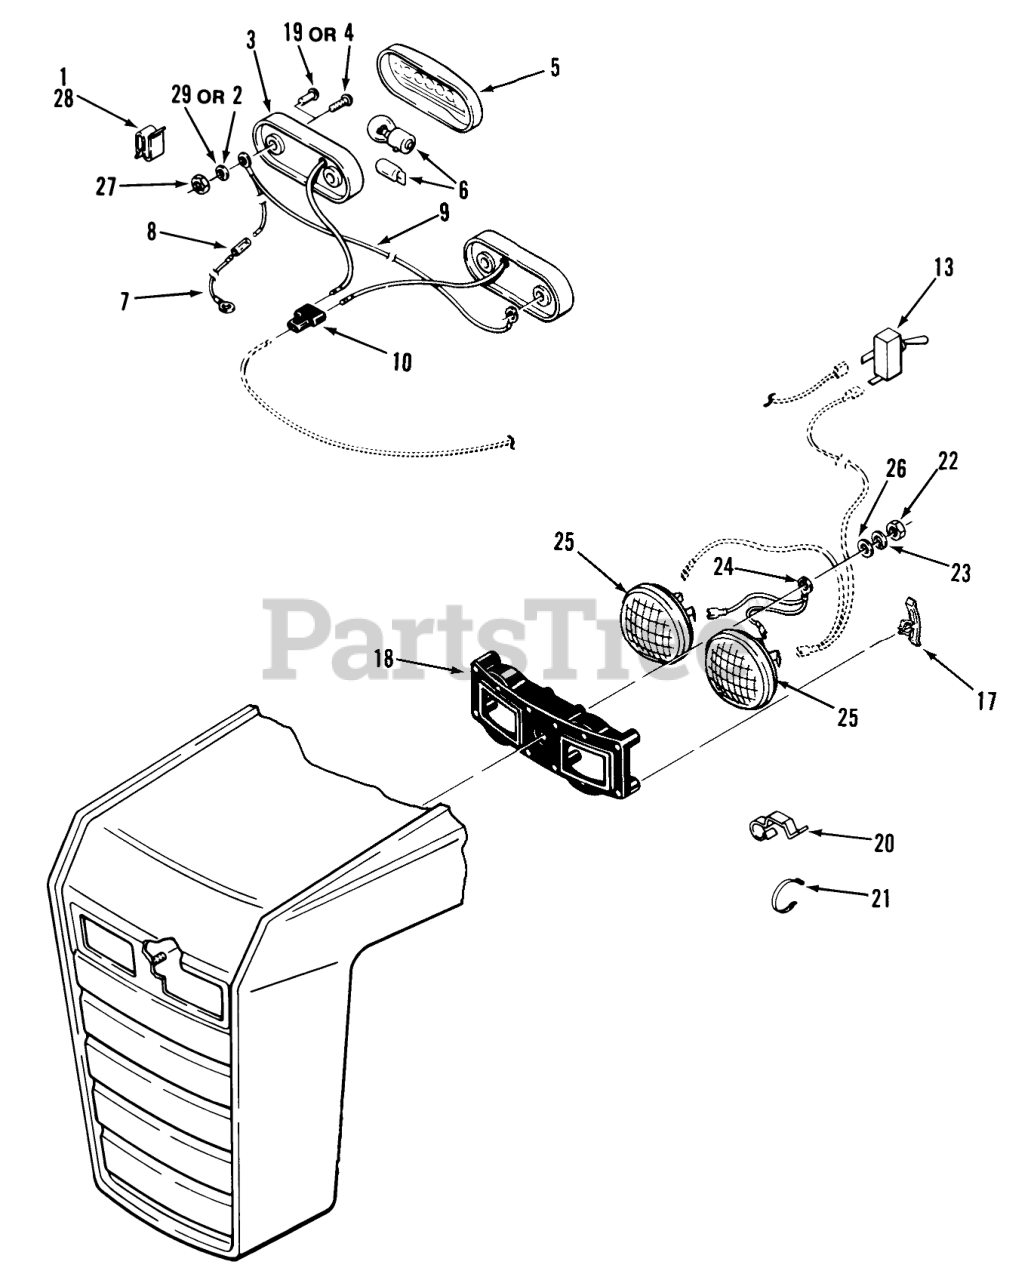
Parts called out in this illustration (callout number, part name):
1	SPEED CLIP
2	Lockwasher
3	BASE-TAIL LIGHT
4	Screw
5	Lens-Taillight
6	Bulb
6	LIGHT BULB
7	ASSEMBLY-WIRE
8	CONNECTOR 2 WIRE
9	Taillight Wire
10	CONNECTOR 3 WIRE
13	SWITCH-LIGHTS
17	CLIP-SPRING
18	Headlight Retainer
19	Poprivet
20	CLIP-WIRE
21	PLASTIC TIE
22	Nut
23	Washer-Lock
24	LIGHT GROUND WIRE
25	HEADLAMP
26	WASHER 5/16 SAE
27	Nut
28	CLIP-CABLE
29	WASHER
